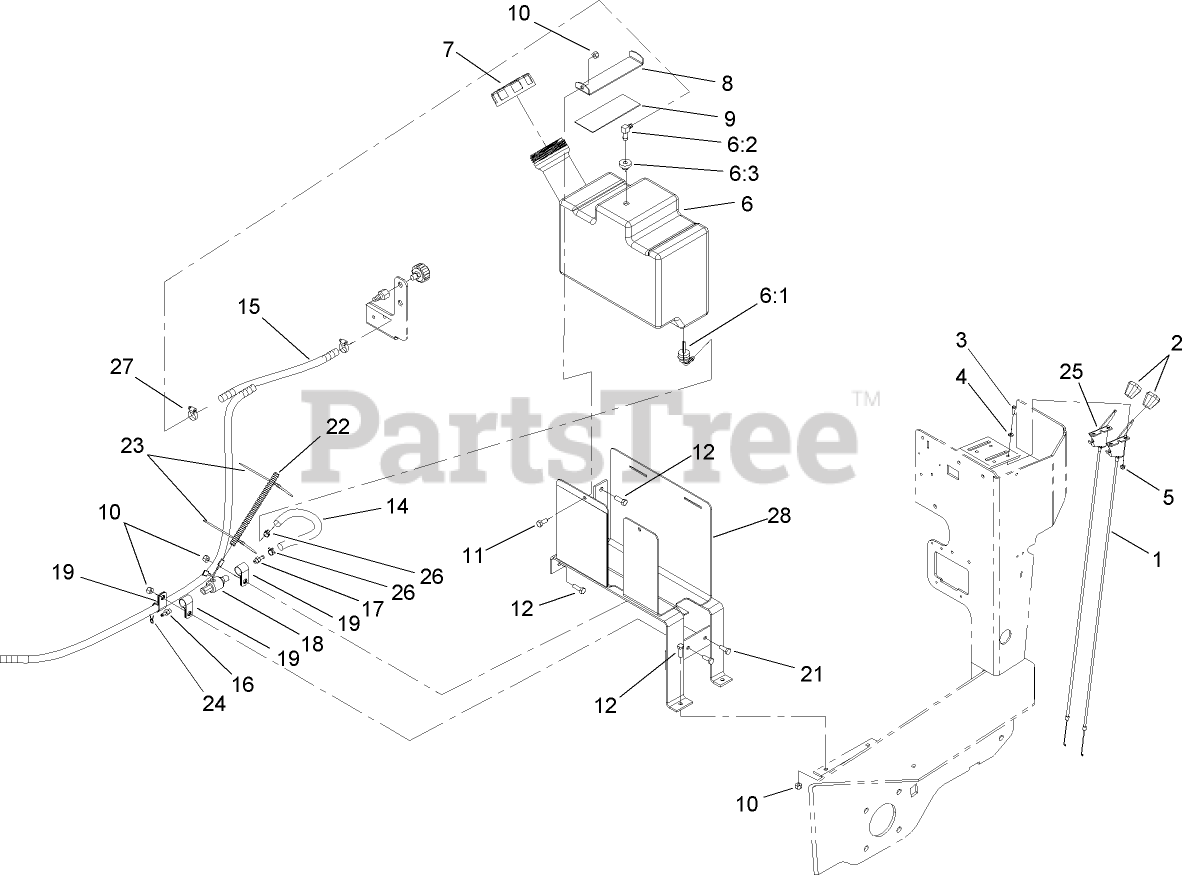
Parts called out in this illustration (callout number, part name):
1	CABLE-CHOKE
4	WASHER-FLAT
5	NUT-LOCK, NI
6	FUEL TANK ASM
6:1	FITTING-FUEL, BULKHEAD
6:2	FITTING-90 DEGREE
6:3	BUSHING
7	UNLEADED GAS CAP ASM
8	STRAP-TANK
9	FELT-STRAP
10	NUT-LOCK, NI
11	SCREW-HH
12	SCREW-HH
14	HOSE - GAS
15	HOSE-FUEL
16	FITTING-BARBED
17	FITTING-STRAIGHT
18	VALVE-SHUTOFF, FUEL
19	CLAMP-R
21	SCREW-HH
22	COVER-BRACE
23	TIE-CABLE
24	CLAMP-HOSE
25	CABLE-THROTTLE
26	CLAMP-HOSE
27	CLAMP-HOSE
28	TANK BRACKET ASM
